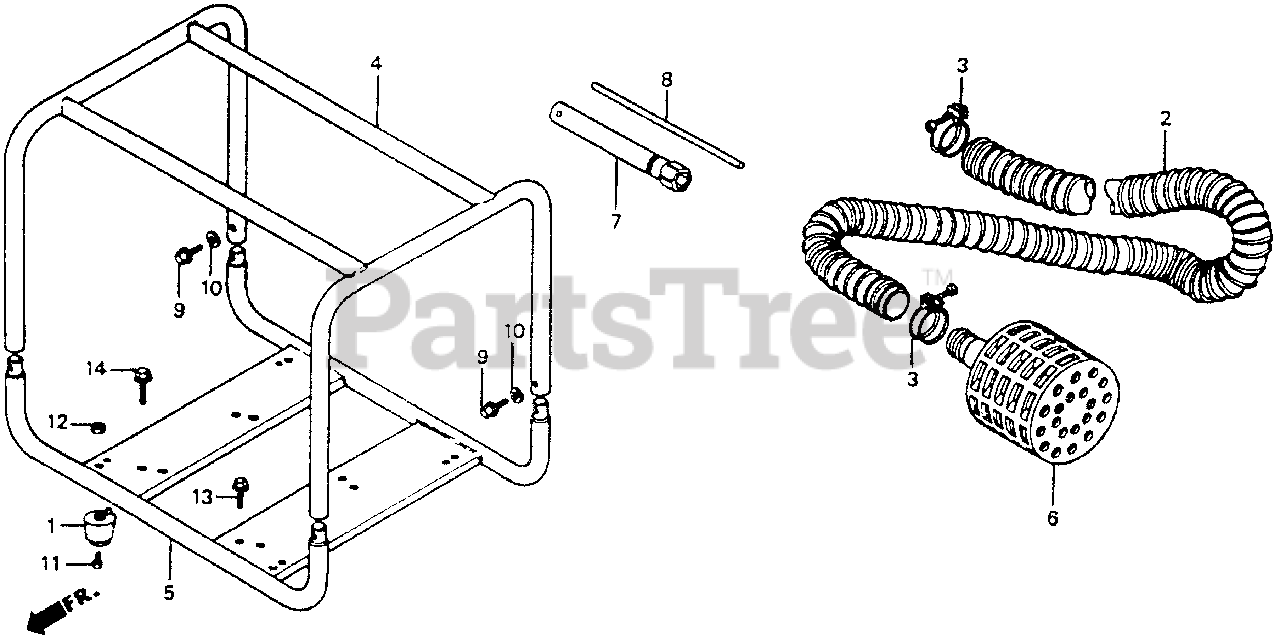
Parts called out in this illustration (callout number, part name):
1	RUBBER (LOWER)
2	HOSE, SUCTION (4.5M)
3	BAND, HOSE
4	FRAME (UPPER)
5	FRAME (LOWER)
6	STRAINER Use up to Frame SN 1835623.
6	STRAINER
7	WRENCH, SPARK PLUG
8	HANDLE, BOX WRENCH
9	BOLT, FLANGE (8X20)
10	WASHER, FRAME JOINT
11	SCREW, PAN (6X10)
12	NUT, HEX. (6MM)
13	BOLT, FLANGE (8X20)
13	BOLT, FLANGE (8X25)
14	BOLT, FLANGE (8X32)
